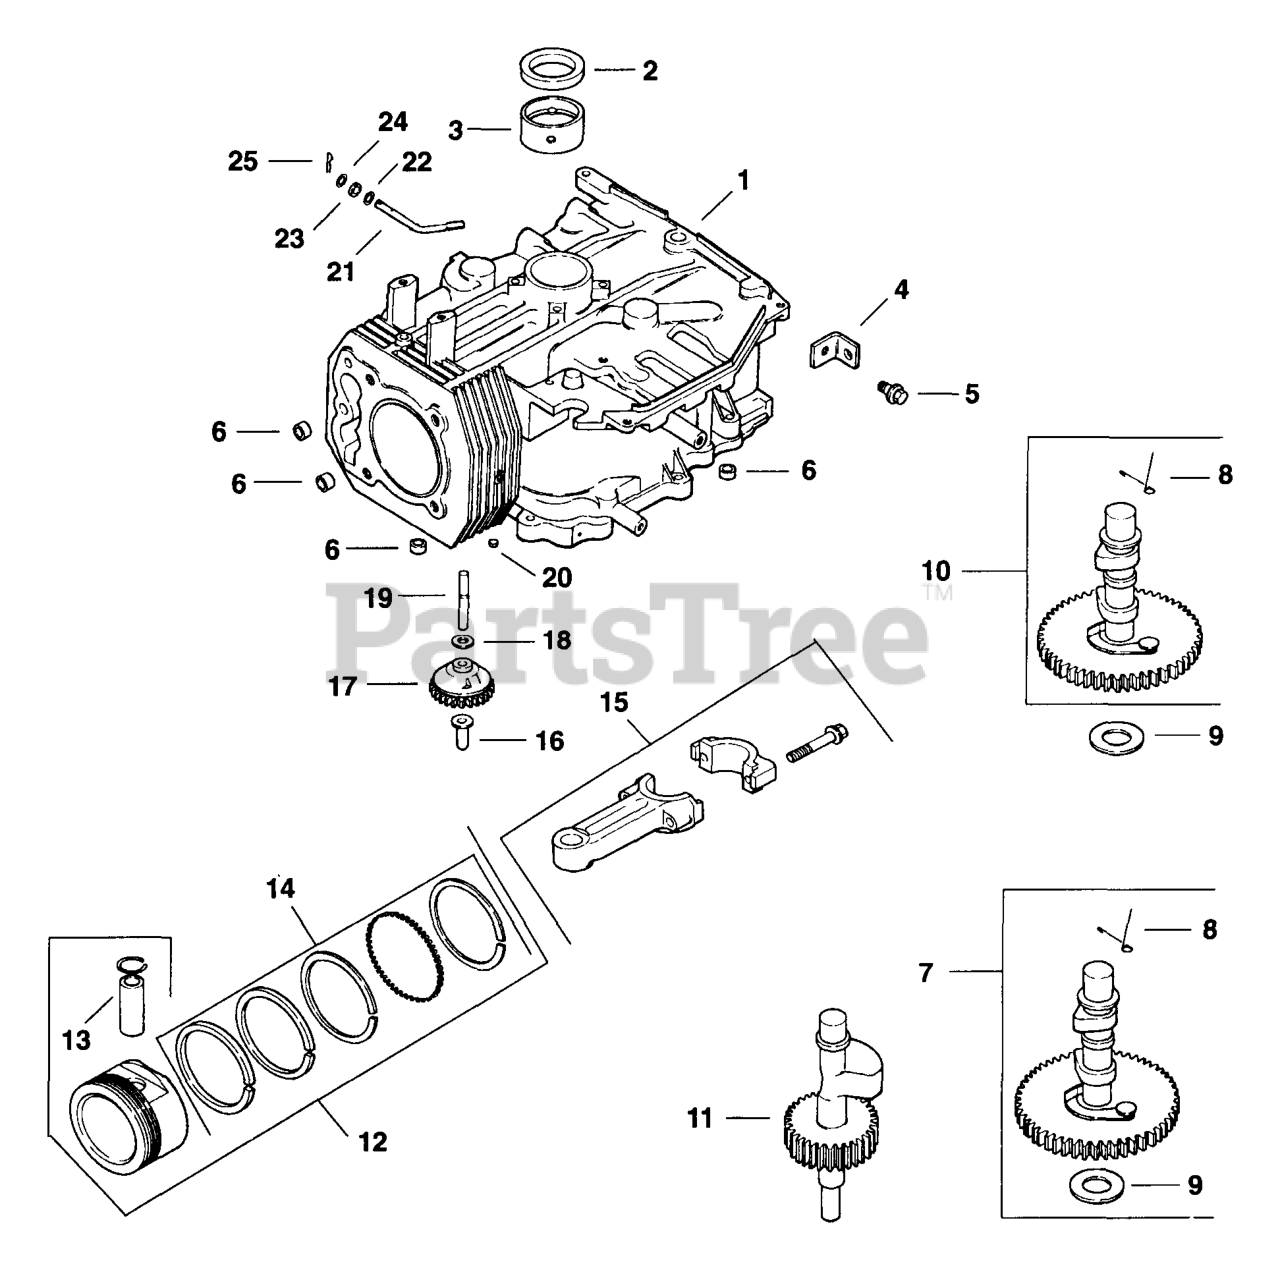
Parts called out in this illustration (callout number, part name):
1	Crankcase
2	Seal, Crankshaft
3	Bearing, Crankshaft (Std.)
3	Bearing, Crankshaft (.25)
3	Bearing, Crankshaft (.50)
4	Strap, Lifting
5	Screw, Lifting Strap M8x1.25x25
6	Dowel, Locating
7	Kit, Camshaft
8	Spring, Actuating (Acr)
9	Shim, Camshaft (Yellow)
9	Shim, Camshaft (Green)
9	Shim, Camshaft (Black)
9	Shim, Camshaft (White)
9	Shim, Camshaft (Blue)
9	Shim, Camshaft (Red)
9	Shim, Camshaft (Gray)
11	Shaft, Balance
12	Piston W/Ring Set (Std.)
12	Piston W/Ring Set (.25)
12	Piston W/Ring Set (.50)
13	Retainer, Piston Pin
14	Ring Set (Std.)
14	Ring Set (.25)
14	Ring Set (.50)
15	Connecting Rod (Std.)
15	Connecting Rod (.25)
16	Pin, Governor Regulating
17	Gear, Governor
18	Washer, Governor Gear Thrust
19	Shaft, Governor Gear
20	Plug, Cup
21	Shaft, Governor Cross
22	Washer, Plain 1/4"
23	Seal, Governor Cross Shaft
24	Washer, Governor Shaft
25	Pin, Governor Hitch
